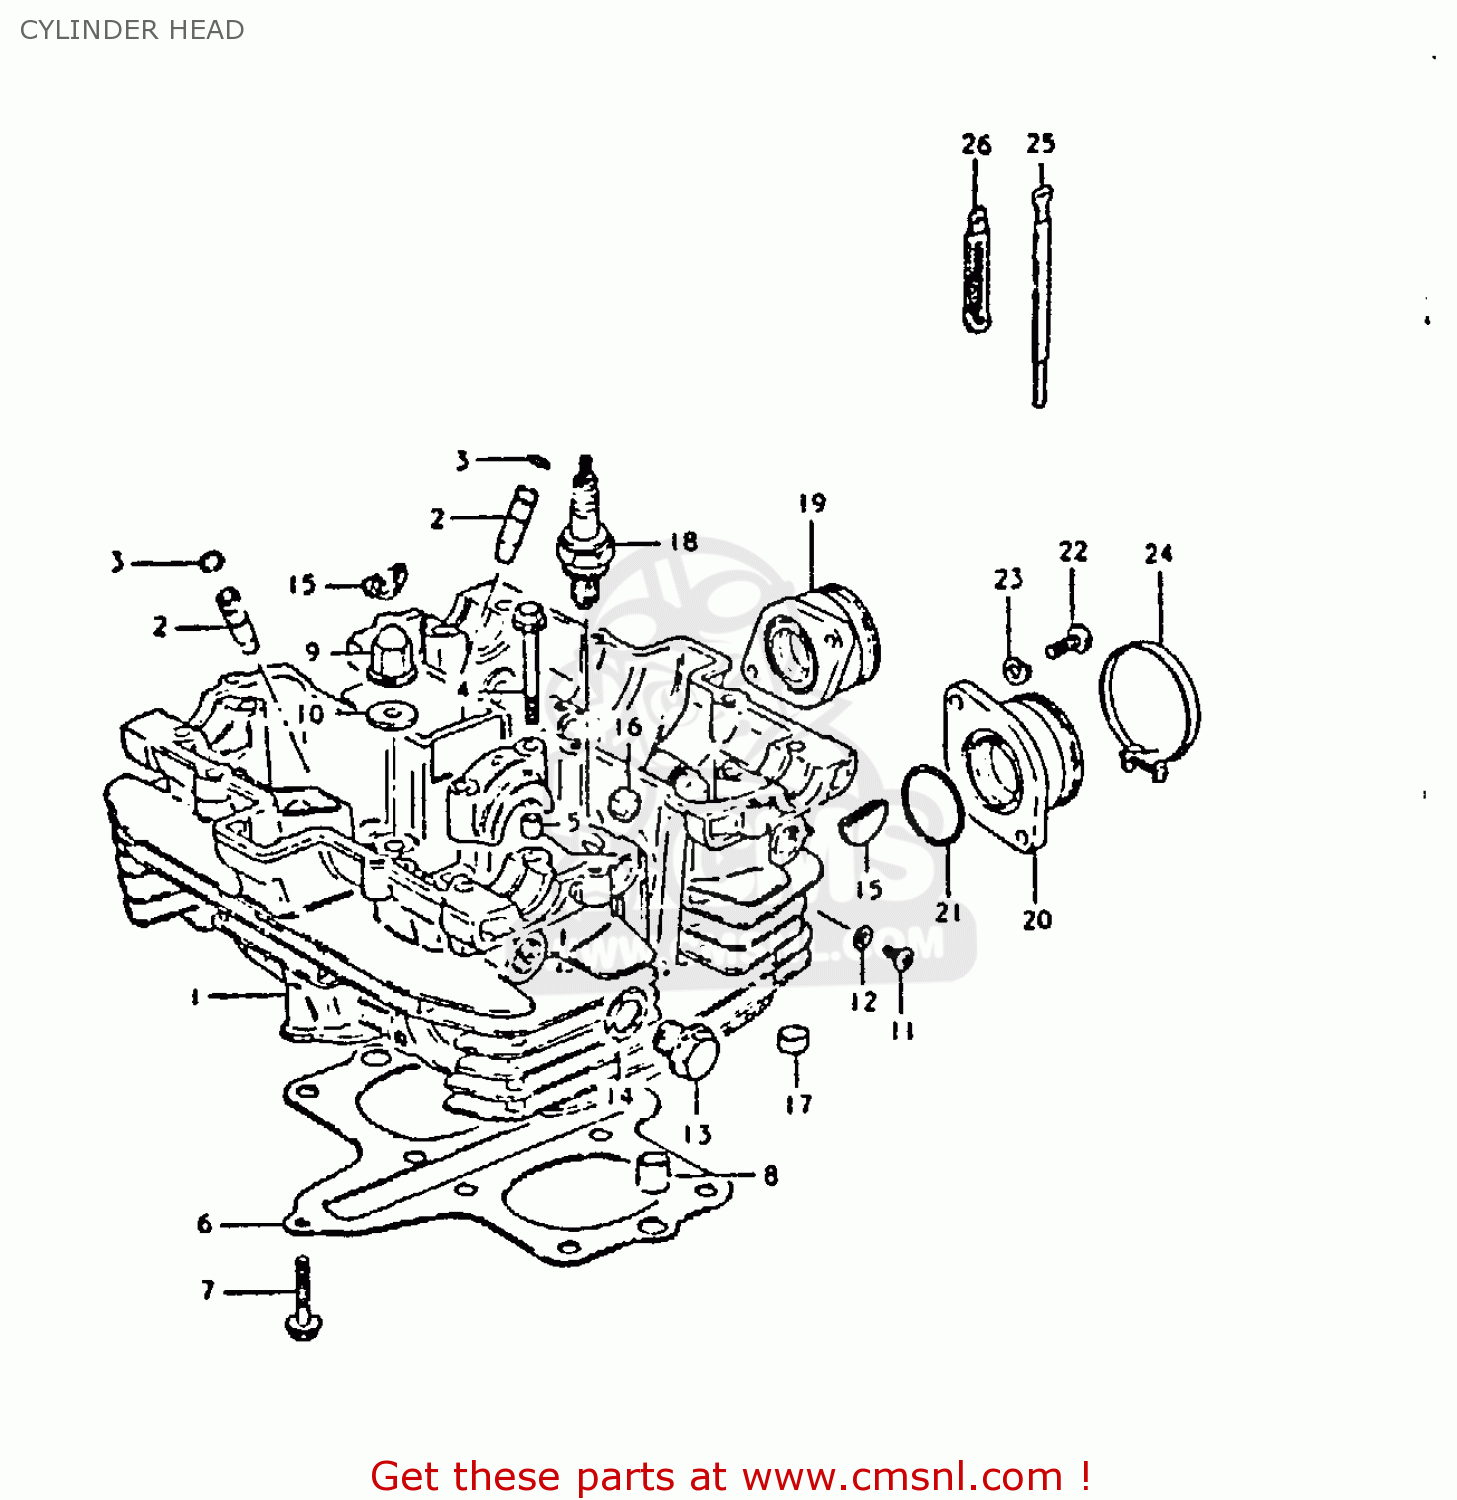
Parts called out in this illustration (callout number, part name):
1	HEAD ASSEMBLY,CYLINDER
2	GUIDE,INTAKE VALVE
3	RING,SNAP
4	BOLT(6X39)
5	PIN(6.2X8X11)
6	GASKET,CYLINDER HEAD (MCA)
7	BOLT
8	PIN
9	NUT
10	GASKET (NAS)
11	SCREW
12	GASKET(5.3X9.3X1.2) (NAS)
13	PLUG (14X12)
14	GASKET(14X19.2X2) (NAS)
15	PLUG
16	PAD,CYLINDER HEAD
17	PAD
18	PLUG,SPARK(DR8ES)
19	PIPE,INTAKE,R
20	PIPE,INTAKE,L
21	O-RING (D:2.4 ID:29.7)
22	SCREW
23	LOCK WASHER
24	CLAMP
25	CLAMP
26	CLAMP
